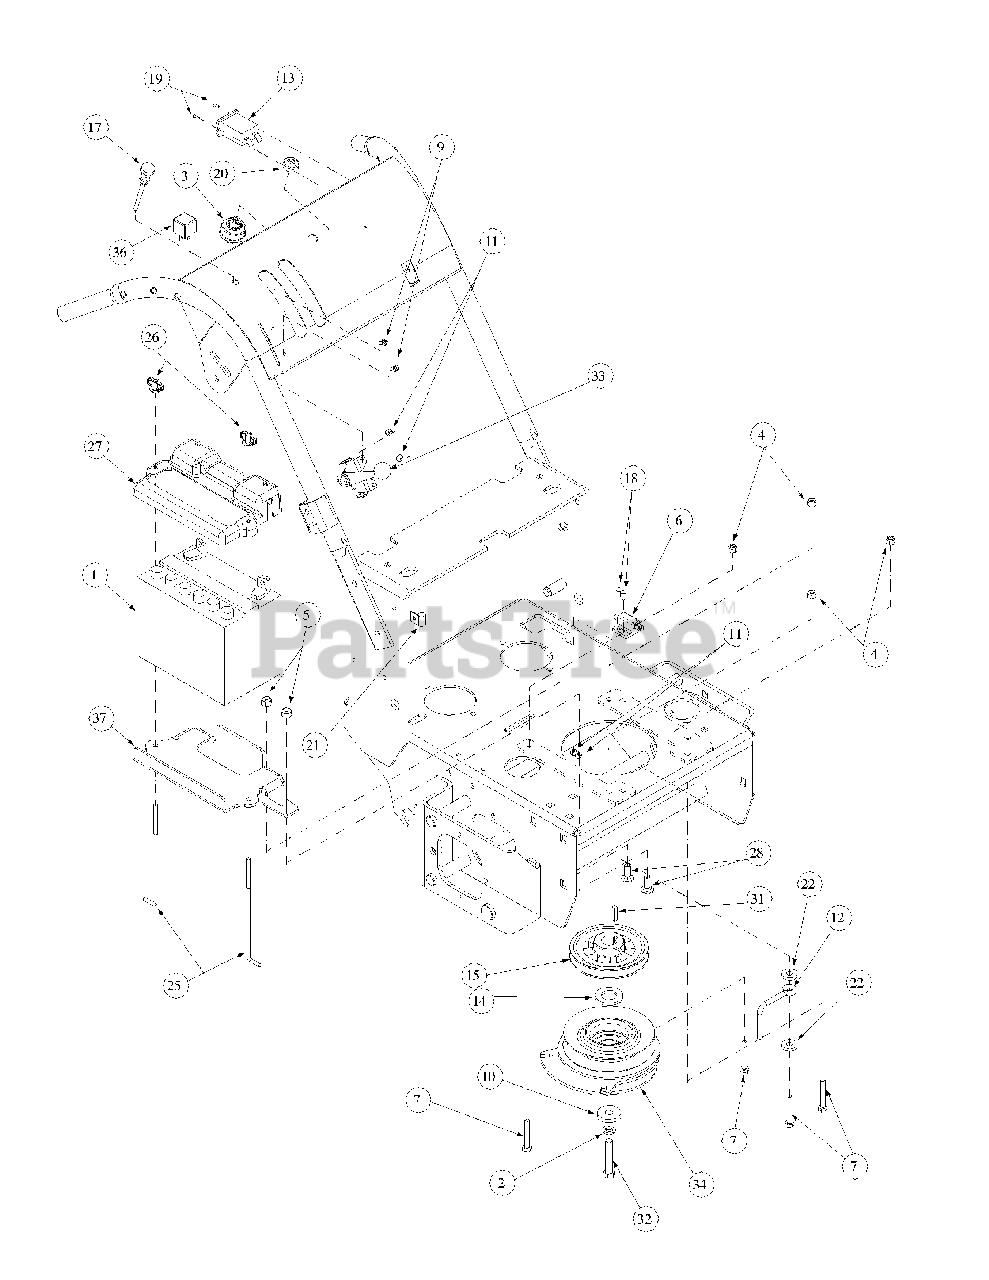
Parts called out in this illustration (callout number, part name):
1	Battery, 12V
2	Lock Washer M10
3	Ignition Switch
4	Nut, 5/16-18, Nylock
5	Lock Nut, Nylon Insert, 3/8-16
6	Switch, Delta
7	Cap Screw, 5/16-18 x 2
7	Boot, Battery Post Red
9	Screw, Hex Washer w/Slot, #10-32 x 1/2
10	Washer Clutch
11	Lock Nut, Nylon Insert, #10-32
12	Guide, Traction Drive Belt
13	Hour Meter
14	Washer, Special
15	Sheave 1" Bore w/2 Set Screws
15	Belt, Hydro Pump
15	Cable Choke
18	Phil. Hd. Mach. Screw, #10-32 x 5/8
19	Rivet
20	Nut, w/Cap, 5/8-32 Ignition
21	Support Clamp, 3/8 OD
22	Washer, Idler
23	Battery Cable, 15", Red
23	Battery Cable, 10", Black
23	Hold Down Rod, Battery
26	Wing Nut, 1/4-20 w/Bell Wash
27	Battery Cover Large
28	Carriage Bolt, 3/8-16 x 2
29	Engine, Kohler, 22 HP Vertical
31	Key, 1/4 x 1/4 x 1
32	Capscrew, M10-1.5 x 60 mm
33	Control Throttle, w/Detent 47.25
34	Brake Clutch
34	Harness Assembly
36	Relay
37	Battery Bracket
